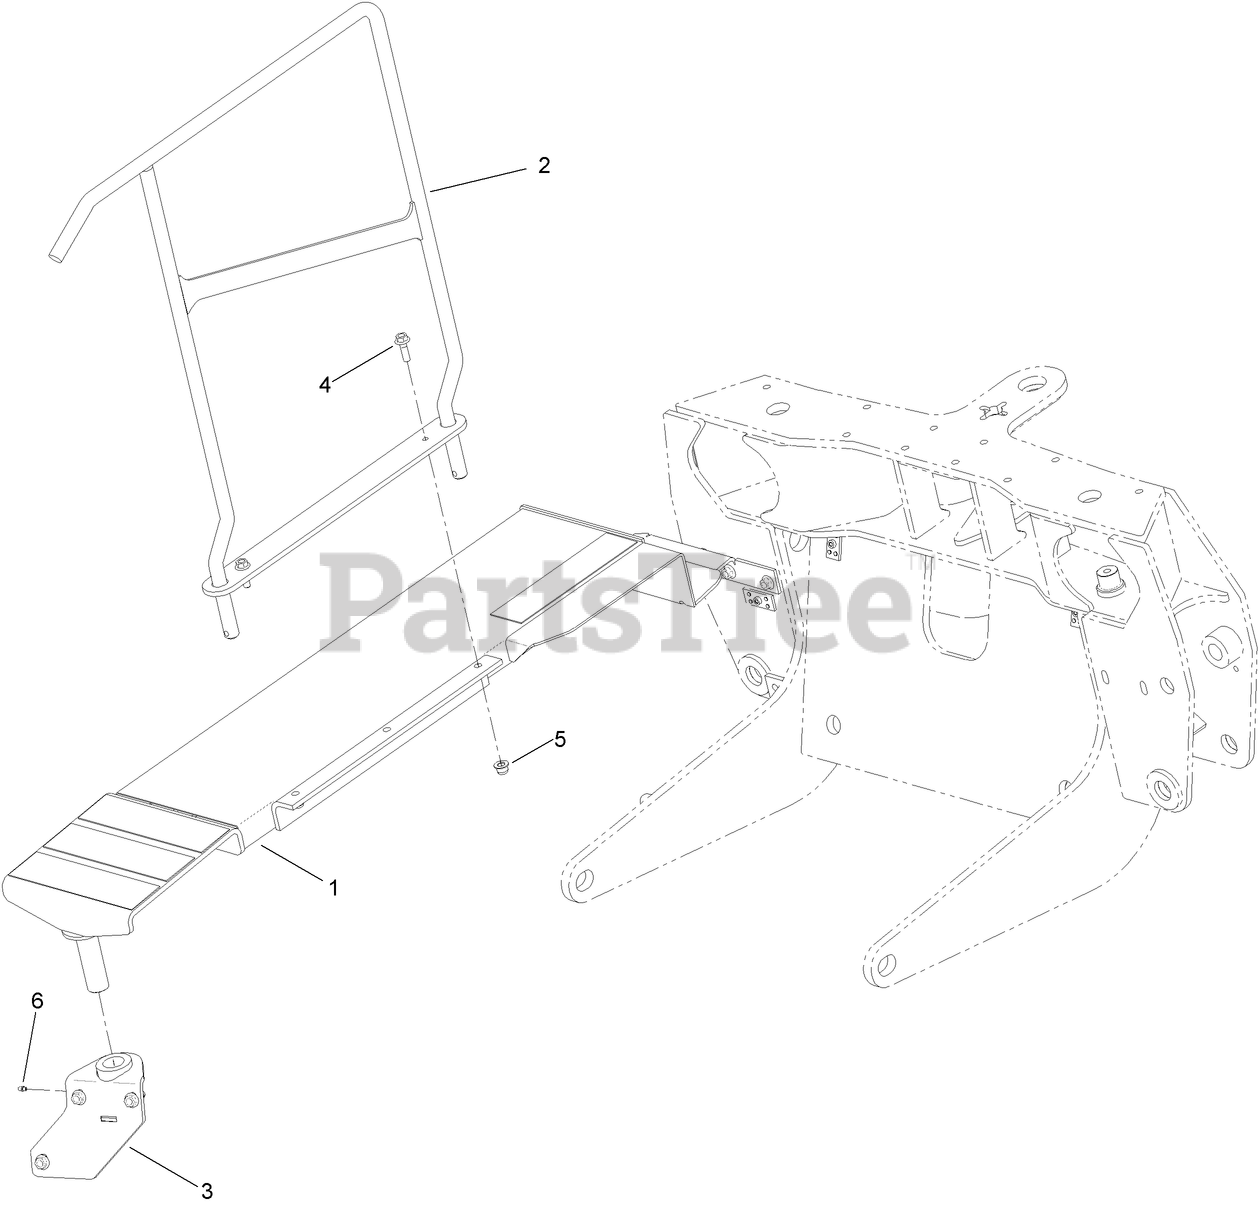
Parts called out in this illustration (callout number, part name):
1	CATWALK ASM
2	Handrail-Catwalk
3	BRACKET-MOUNT, WALKWAY
5	NUT-HHF, LOCK
6	FITTING-GREASE
